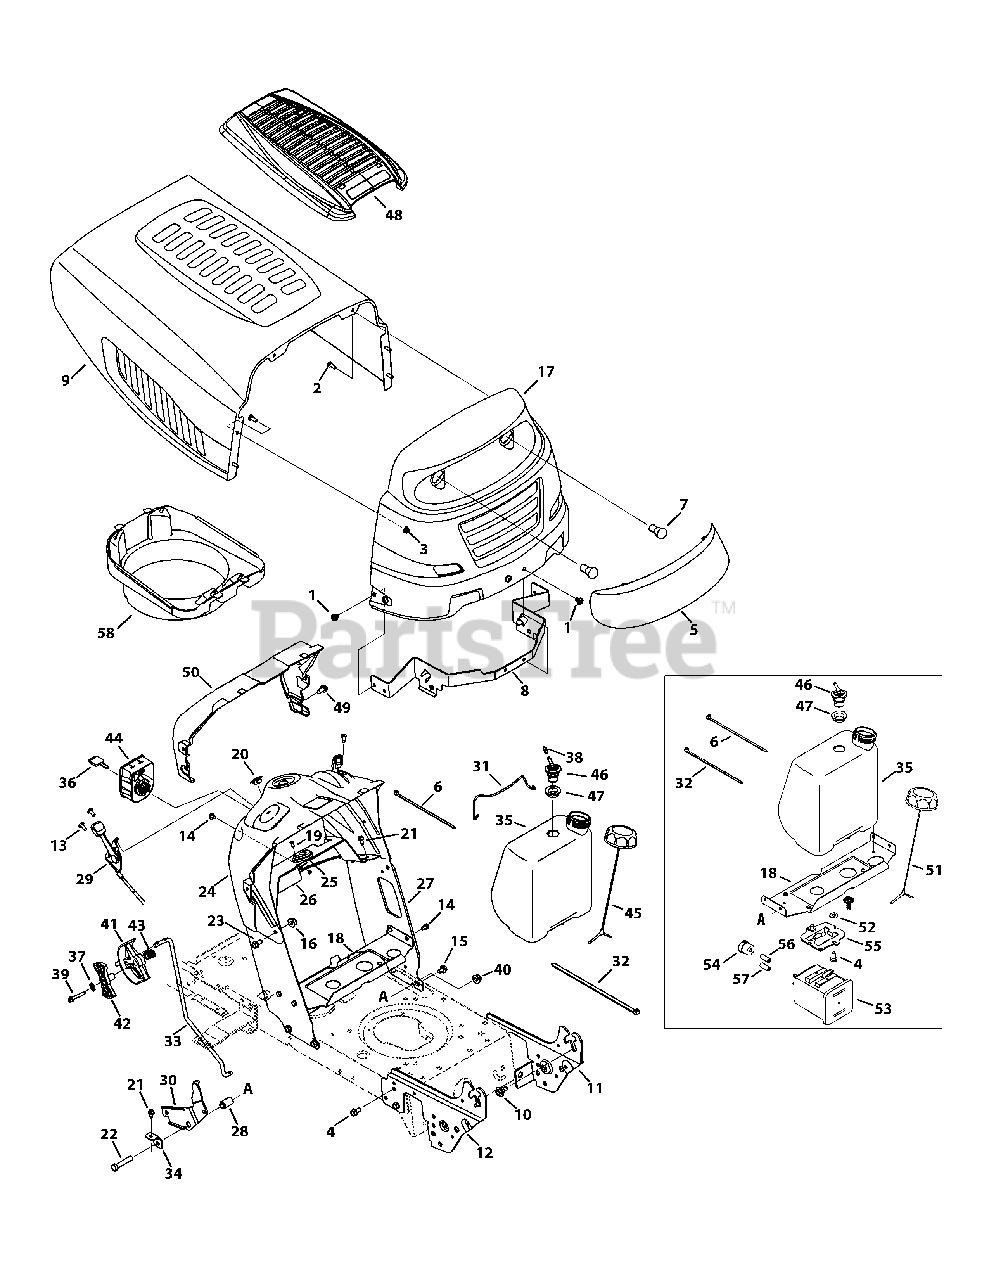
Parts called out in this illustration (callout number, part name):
1	Screw, 5/16-18 x .375
2	Hex Screw, 1/4-20 x .620
3	Flangelock Nut, 1/4-20
4	Screw, 5/16-18 x .750
5	Grill Lens
6	Cable Tie
8	Hood Pivot Bracket
10	Shoulder Screw, 5/16-18 x .43 x .29
11	Left Support Pivot Bracket
12	Right Support Pivot Bracket
13	Screw, 1/4-20 x .500
14	Screw, 1/4-20 x .500
15	Screw, 5/16-18 x .625
16	Flangelock Nut, 5/16-18
18	Gas Tank Support Bracket
19	Screw, #10-16 x .500
20	Choke Plug
21	Tap Screw, 1/4-20, 0.625
22	Hex Screw, 3/8-16 x 2.0
23	Hex Screw, 5/16-18 x .625
24	Dash, Upper
24	Dash, Upper No RMC
25	Bearing, .628 ID x 1.36
26	Bracket, Steering Support
27	Dash, Lower
28	Flange Spacer, .390 x .671 x 1.095
29	Throttle/Choke Cable
30	Speed Latch - No RMC
31	Battery Assembly Rod
32	Cable Tie
33	Speed Control Rod
34	Speed Latch Tab
35	1.36 Gallon Fuel Tank
36	Key, Assembly
37	Lock Washer, 1/4
38	Hose Vent, 3/16 EPA
39	Hex Washer Screw, 1/4-20 x 1.50
40	Flangelock Nut, 3/8-16
41	Shift Lever
42	Index Control
43	Compr. Spring, .72 OD x .78
44	3 Position Key Switch
45	Fuel Cap, 2.25"
46	Rollover Valve
47	Rubber Grommet, 23 x 3.55
48	Hood Scoop
49	Screw, 1/4-15 x .750
50	Dash Collar
51	Fuel Cap, 2.25"
52	Flat Washer, .344 x .750 x .120
53	5 Gallon Carbon Canister
54	Vent Filter Canister
55	Canister Adaptor Bracket
56	Hose, Fuel, Low Perm., White
57	Hose, Fuel, Low Perm., Yellow
